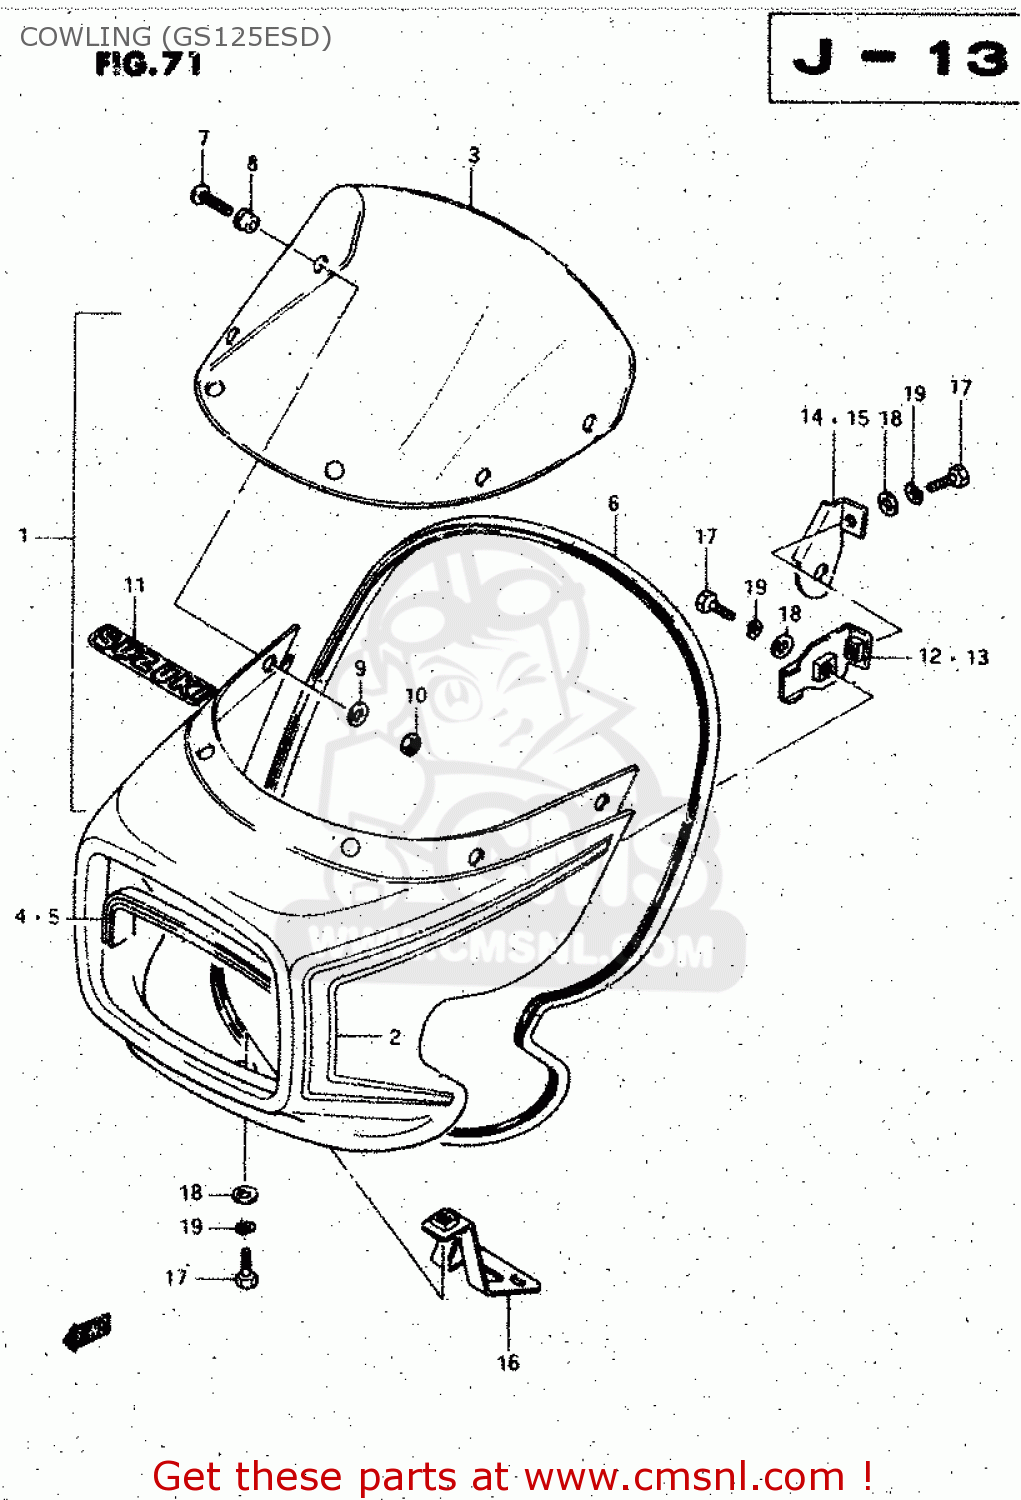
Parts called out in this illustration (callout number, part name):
1	COWLING ASSY (RED)
2	TAPE SET
3	WINDOW,COWLING
4	MOLDING,HEADLAMP GRILL
5	MOLDING,HEADLAMP GRILL
6	MOULDING, WINDOW
7	SCREW, FRONT & REAR
8	CUSHION
9	WASHER,5MM
10	NUT ,5MM
11	EMBLEM (GOLD/BLACK)
12	BRACE, RH (L:19)
13	BRACE,COWLING LH
14	BRACKET, FITTING RH (L:19)
15	BRACKET,L
16	BRACKET, LOWER
17	BOLT 6X16
18	WASHER (6.5X18X1.6)
19	WASHER,LOCK
